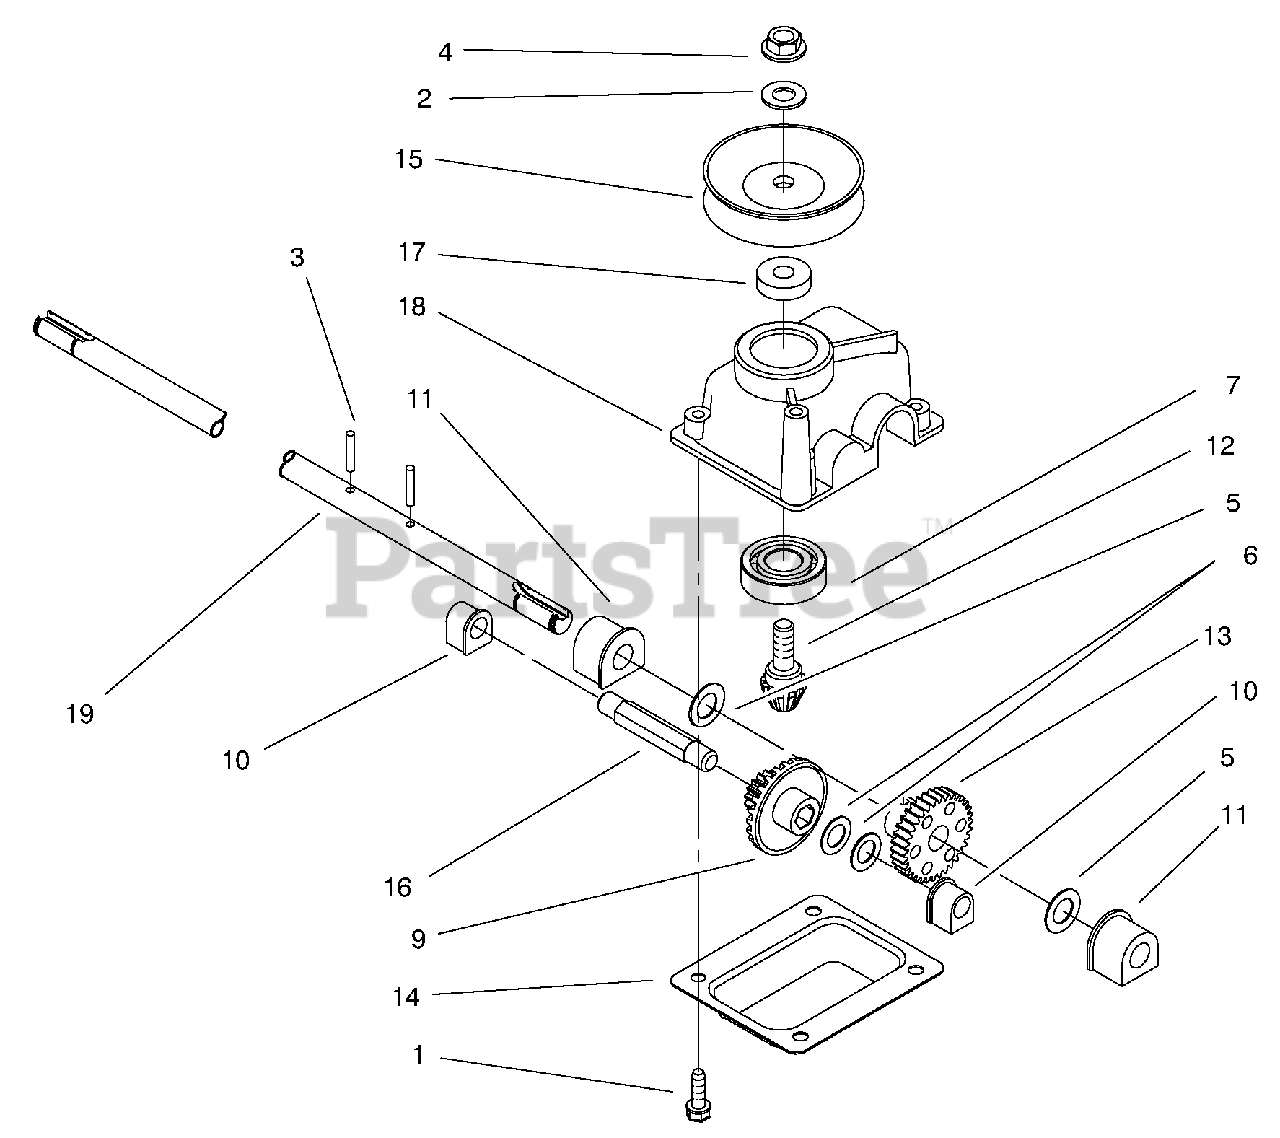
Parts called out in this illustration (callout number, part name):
1	Screw-HH
2	Washer-Flat
3	Pin-Groove
4	Nut-Lock NI
6	Thrust Washer
7	Bearing-Ball
9	Gear-15T Spur, 37T Bevel
11	Bushing-Output
12	Bevel Pinion Gear
13	Gear -34T
14	Gear Case Cover
15	Pulley Half
16	Shaft-Intermediate
18	Gearcase
19	Shaft-Output
